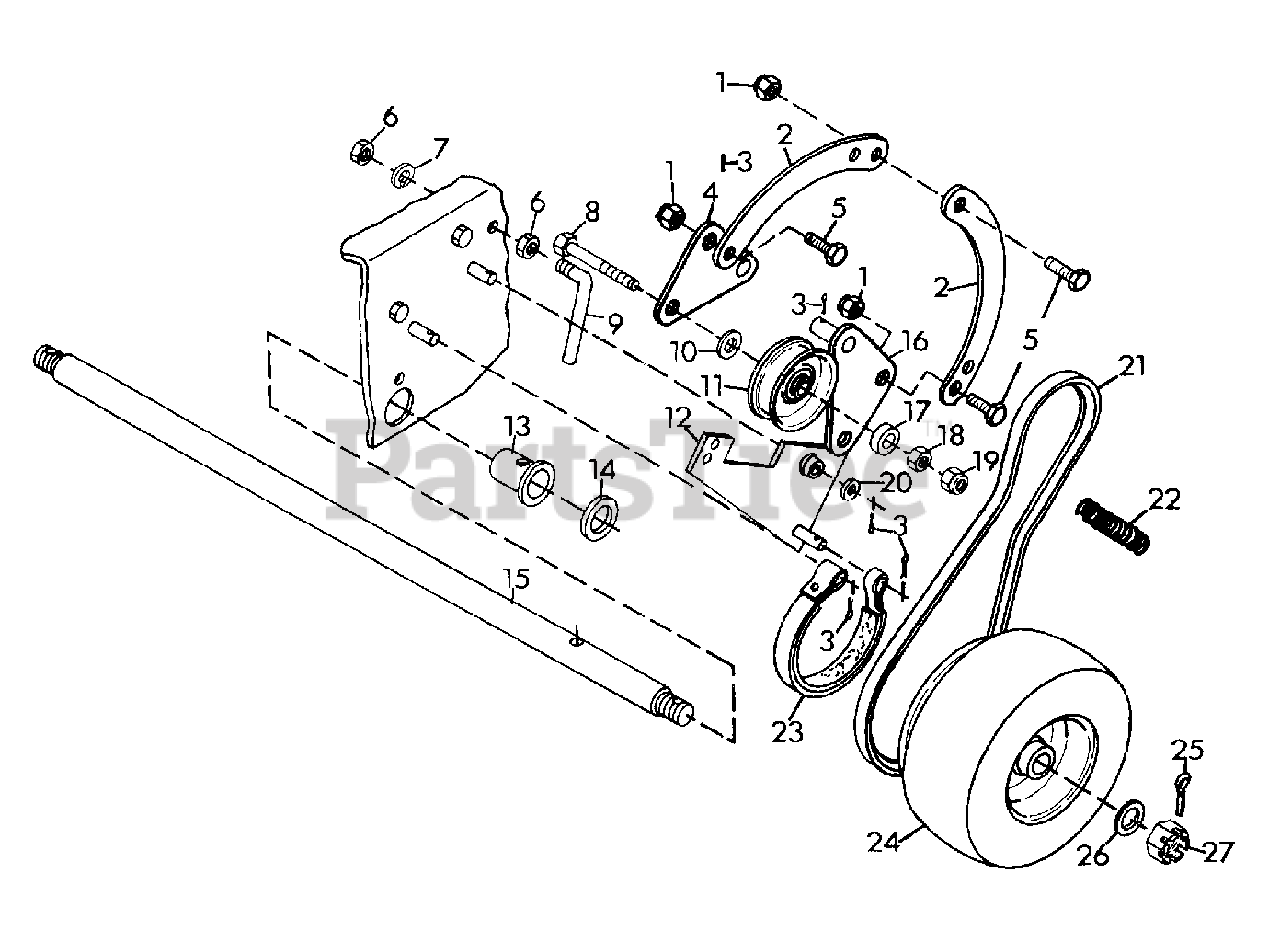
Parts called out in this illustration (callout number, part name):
1	NUT, LOCK 5/16-18
2	STRAP, WHEEL CLUTCH ACTUATING
3	PIN, COTTER .125X1.00
4	WELDMENT, WHEEL CLUTCH L.H.
5	BOLT, HEX 5/16-18X.625
6	NUT, HEX 1/4-20
7	WASHER, LOCK 1/4 REG.
8	BOLT, HEX 3/8-16X2.00
9	ROD, PULLEY CLEANING
10	WASHER, FLAT .406X.812X.065
11	SHEAVE, IDLER
12	WELDMENT, BRAKE LEVER L.H.
12	WELDMENT, BRAKE LEVER R.H.
13	BUSHING, PIVOT
14	SPACER, WHEEL
15	SHAFT, AXLE
16	WELDMENT, WHEEL CLUTCH R.H.
17	SPACER, IDLER
18	NUT, HEX 3/8-16
19	NUT, LOCK 3/8-16
20	WASHER, FLAT .344X.688X.065
21	BELT, TRACTION
22	SPRING
23	ASSEMBLY, BRAKE BAND L.H.
23	ASSEMBLY, BRAKE BAND R.H.
24	ASSEMBLY, PRO WHEEL AND TIRE
25	PIN, COTTER .156X1.50
26	WASHER, FLAT .813X1.37X.100
27	NUT, SLOTTED 3/4-16
